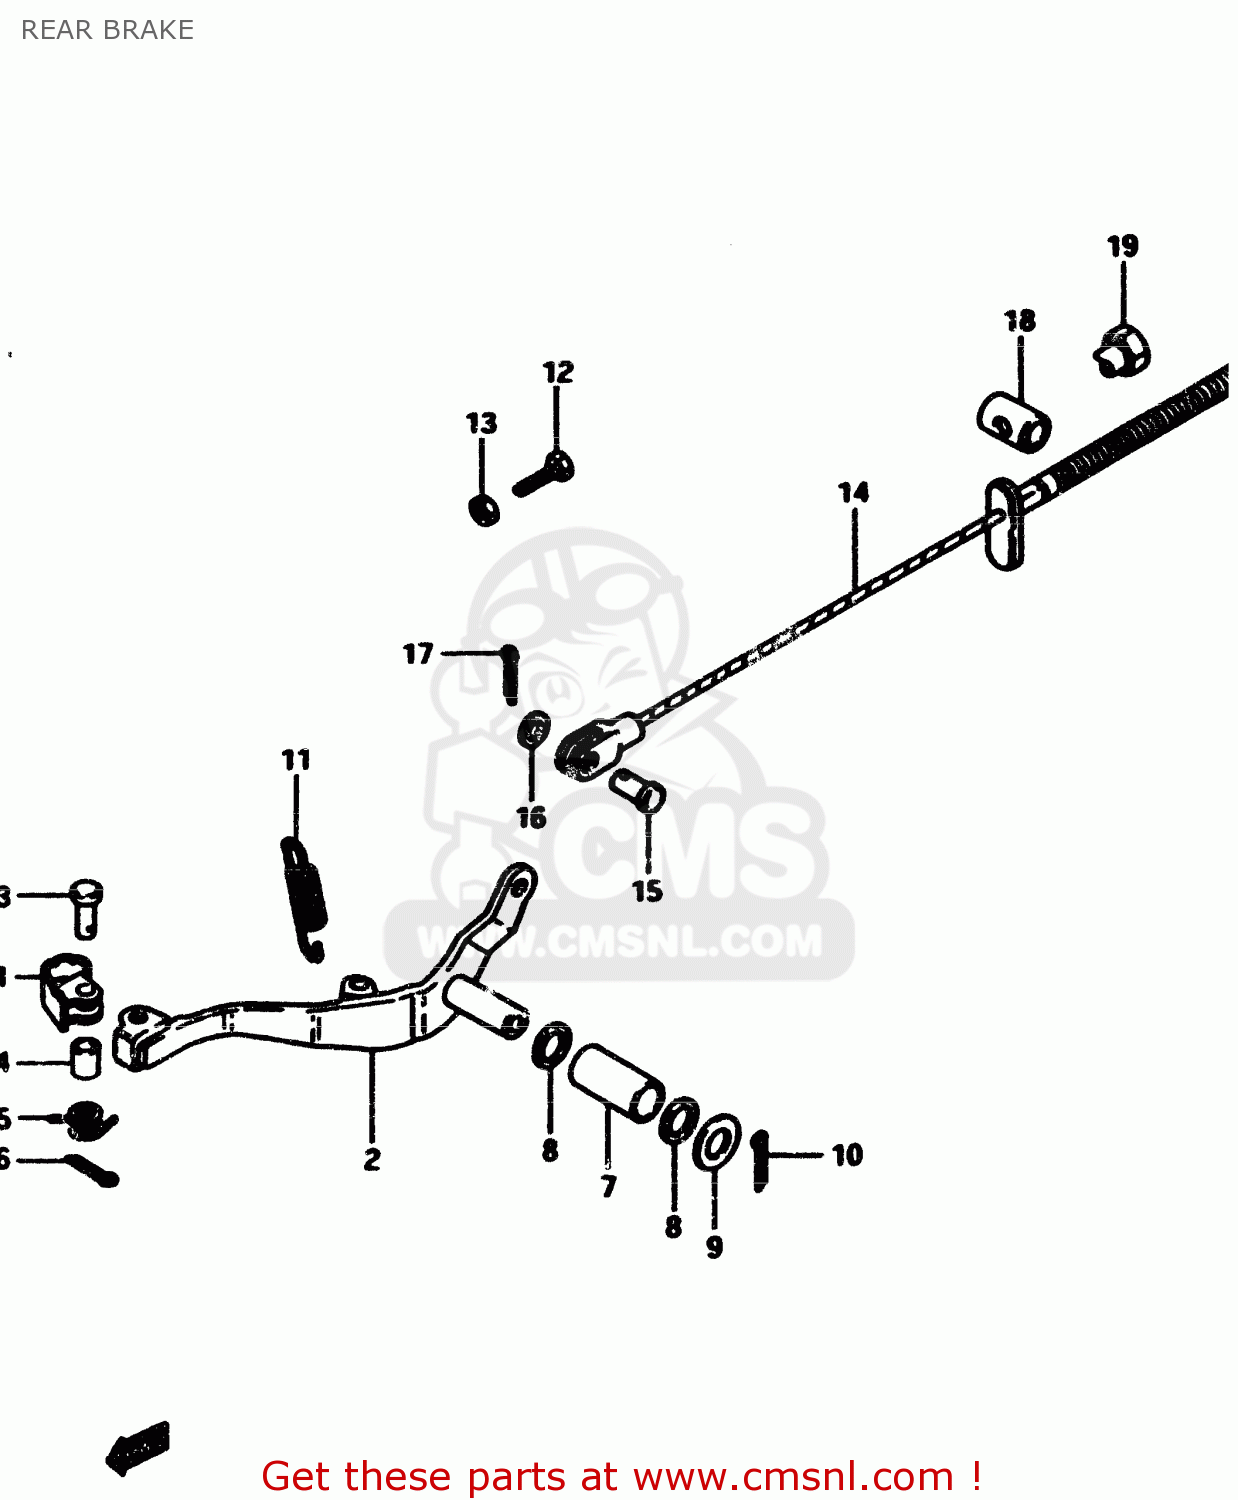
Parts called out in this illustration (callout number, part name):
1	PEDAL,BRAKE
2	ARM,BRAKE PEDAL
3	PIN
4	SPACER(9.2X9X6.5)
5	SPRING
6	PIN
7	BUSHING
8	O RING(D:2.2,ID:11.8)
9	WASHER
10	PIN 30X20
11	SPRING
12	SCREW(6X23)
13	NUT
14	CABLE ASSEMBLY,REAR BRAKE
15	PIN(L:17.5)
16	WASHER
17	PIN 20X20
18	PIN
19	NUT (6MM)
